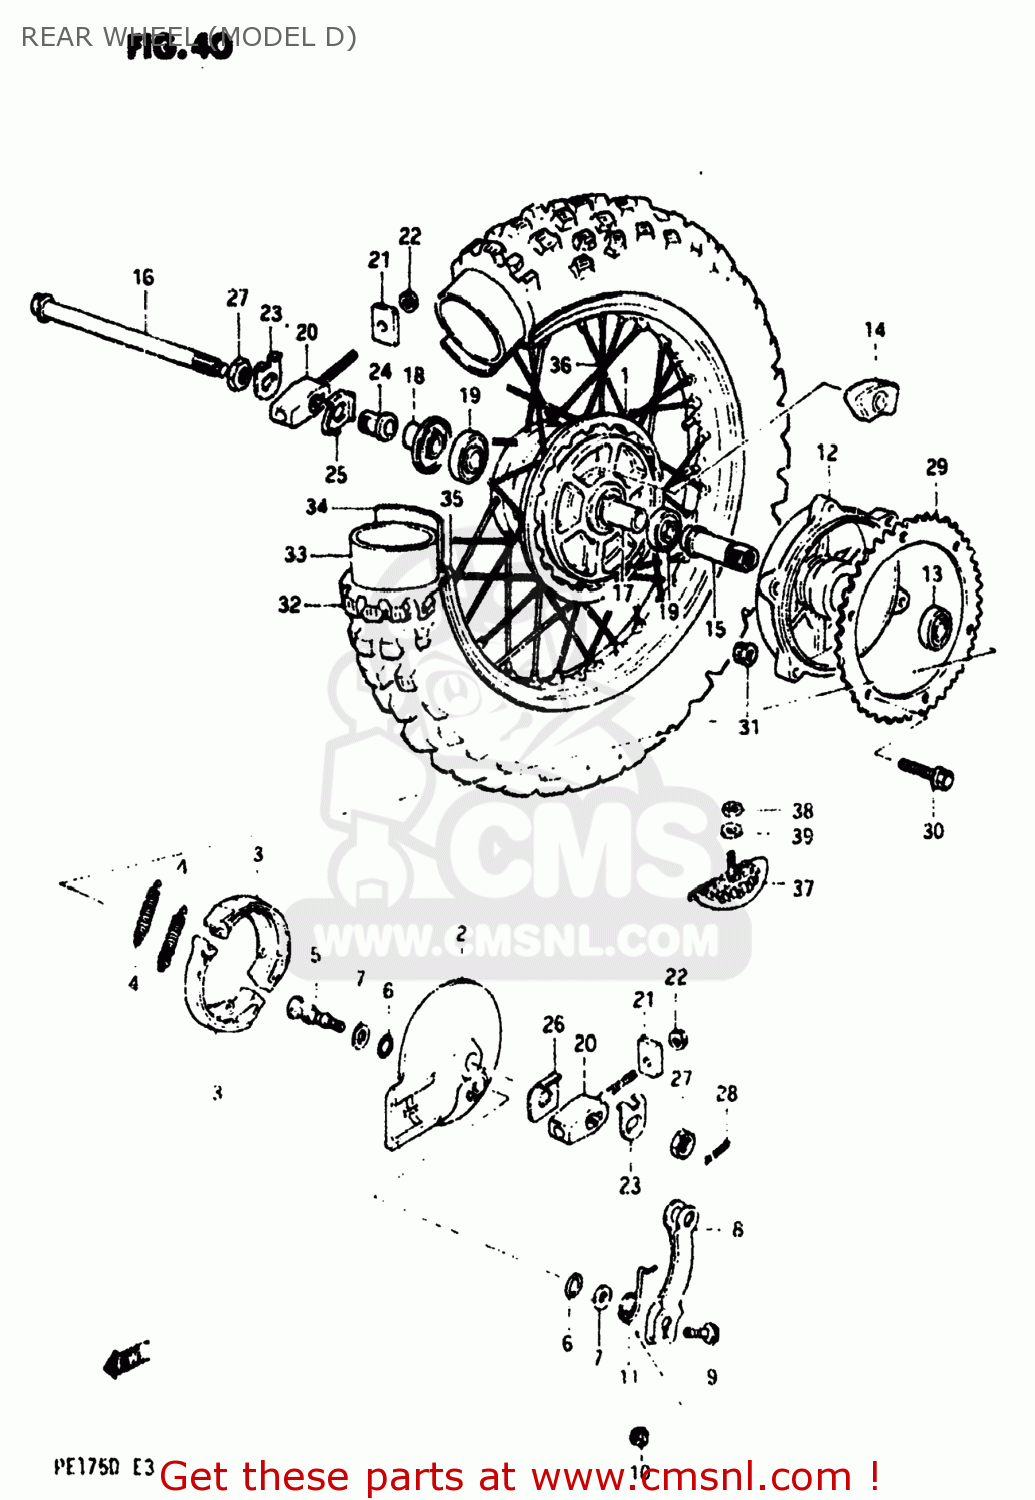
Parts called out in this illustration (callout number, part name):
1	HUB,REAR WHEEL
2	PANEL,REAR HUB
3	SHOE,BRAKE
4	SPRING(L:34)
5	CAM,REAR BRAKE
6	O-RING (D:2.4 ID:13.8)
7	WASHER (14.5X22X1.6)
8	LEVER,REAR BRAKE CAM
9	BOLT
10	NUT
11	SPRING
12	DRUM ASSEMBLY,REAR BRAKE
13	BALL BEARING 22X50X14
14	ABSORBER,RR HUB SHOCK
15	SHAFT,REAR BRAKE DRUM
16	AXLE,REAR
17	SPACER,REAR HUB BEARING
18	SPACER,REAR AXLE,RIGHT
19	BEARING
20	ADJUSTER,CHAIN
21	PLATE,CHAIN ADJUSTER GUIDE,R
22	NUT
23	WASHER,CHAIN ADJUSTER GUIDE
24	SPACER,CHAIN ADJUSTER
25	PLATE,CHAIN ADJUSTER,RIGHT
26	PLATE CH ADJUSTER LH
27	NUT
28	PIN 30X20
29	SPROCKET,REAR (NT:48)(AL)
30	BOLT(8X30)
31	NUT
32	TIRE
33	TUBE ASSEMBLY,WHEEL,INNER
34	PROTECTOR,WHEEL,INNER
35	RIM,REAR WHEEL
36	SPOKE SET,REAR
37	STOPPER,BEAD
38	NUT
39	WASHER
